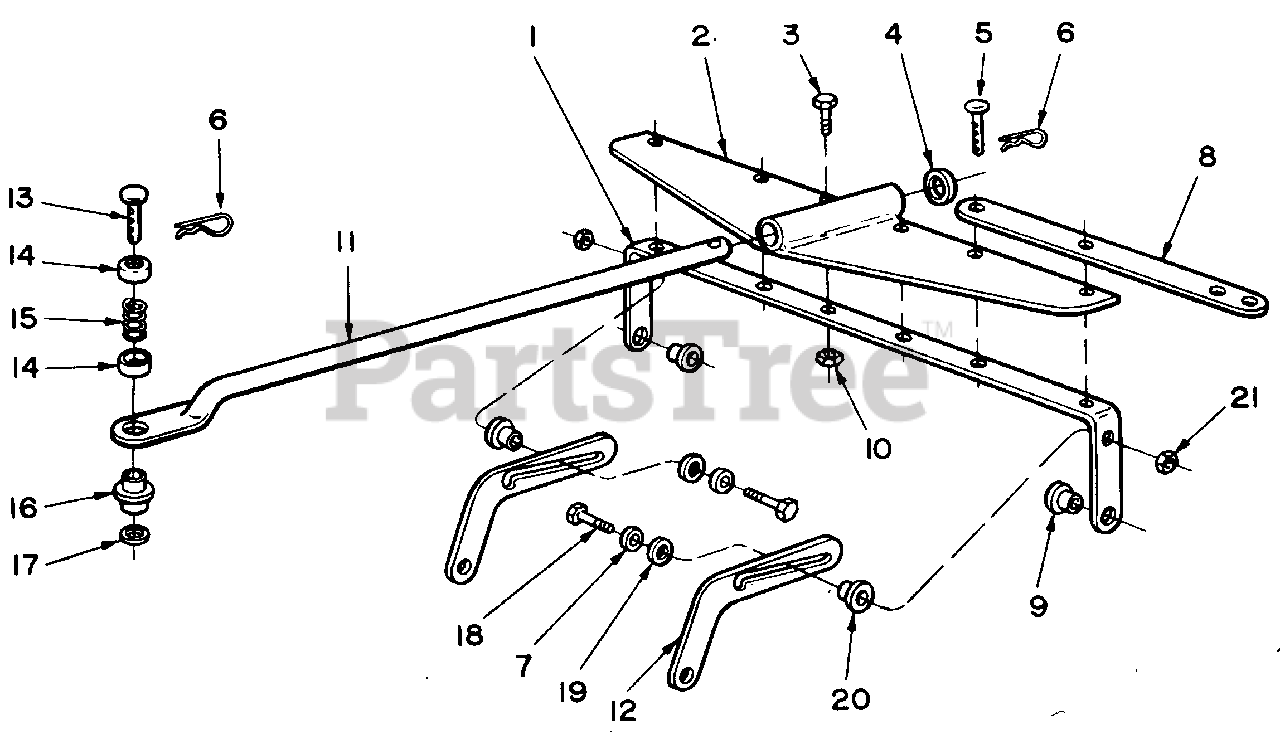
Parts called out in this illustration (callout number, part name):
1	Bridge
2	Tow Bar Plate Ass'y.
3	Bolt 5/16x 18x 1*
4	Washer
5	Clevis Pin
6	Cotter Pin
7	Washer- Special
8	Outrigger Bar
9	Spacer Bushing
10	Nut5/16-18*
11	Tow Bar Ass'y.
12	Transport Brkt.
13	Clevis Pin
14	Spring Cup
15	Spring
16	Bushing
17	Washer 11/32 x 7/8*
18	Shoulder Bolt
19	Washer
20	Spacer
21	Hex L-Nut 1/4- 20*
